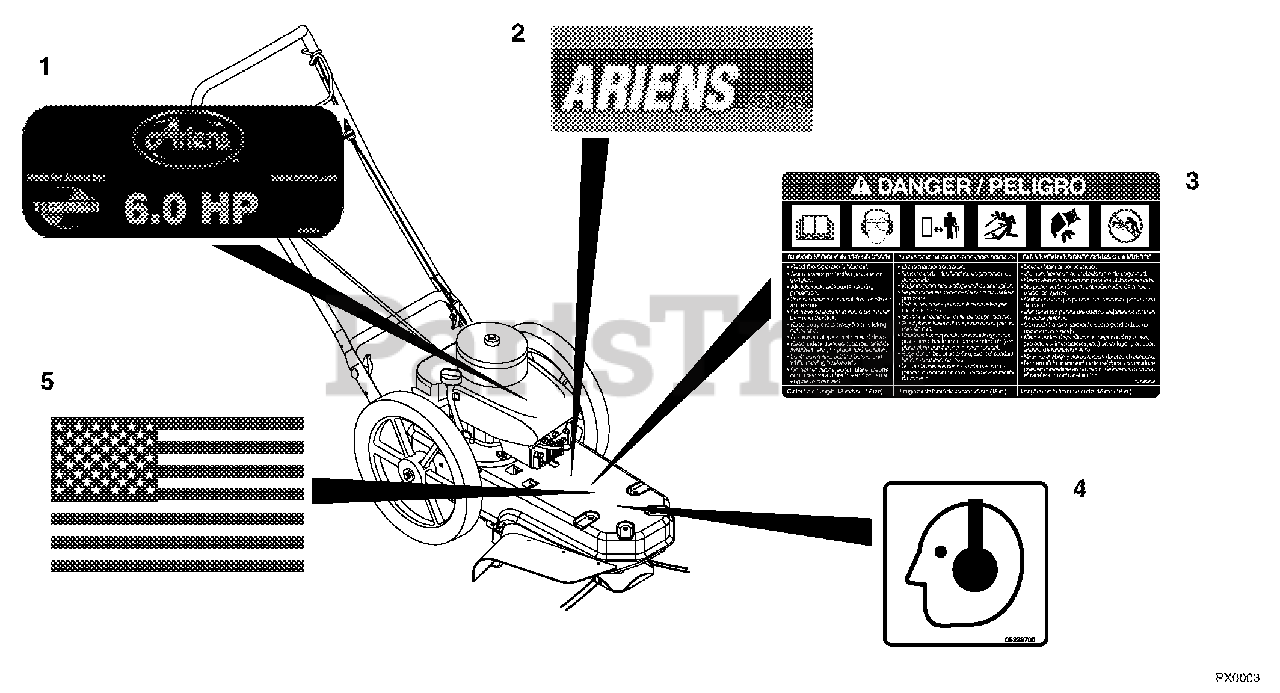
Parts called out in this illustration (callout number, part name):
1	DECAL - 6 HP ARIENS/TEC
2	DECAL - ARIENS ST 622
3	DECAL - DANGER-STRING TRIMMER
4	DECAL - EAR PROTECTION
5	DECAL, AMERICAN FLAG
